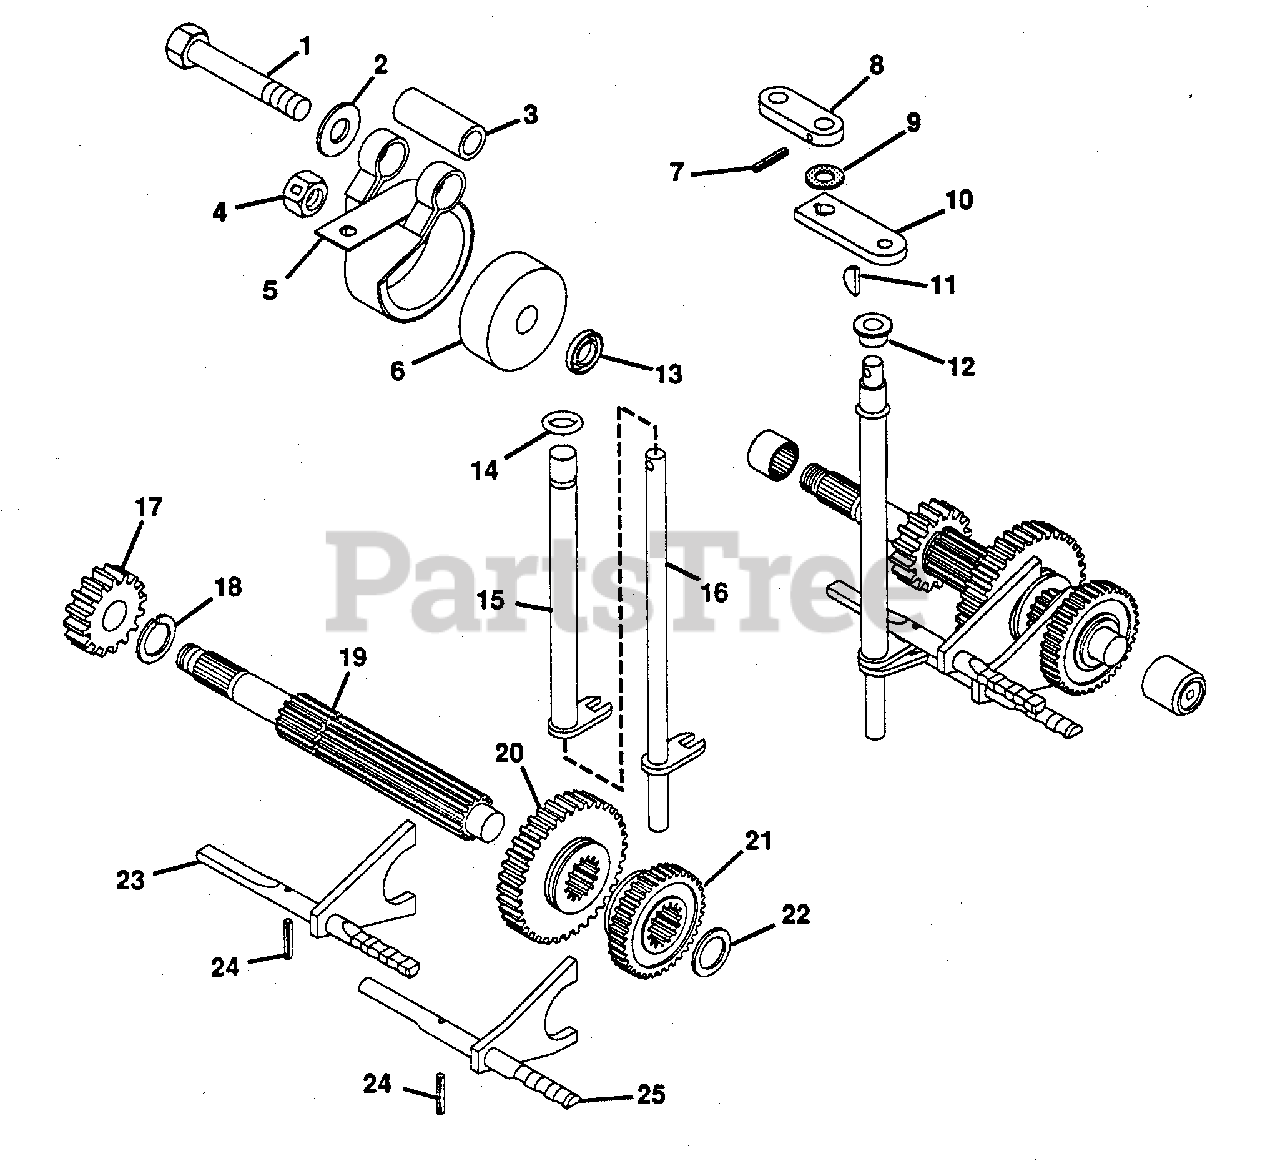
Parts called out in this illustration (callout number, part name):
1	Bolt, Hex 1/2-13 x 2.75
2	Washer, Flat .531 x 1.062 x .095
3	Bushing, .530 x .750 x 2.06
4	Nut, Lock 5/8-11
5	Assembly, Brake Band
6	Drum, Brake
7	Pin, Spring .188 x 1.000
8	Arm, Shifter
9	Washer, Felt (Special for Trans.)
10	Arm, Shifter
11	Key, Woodruff .125 x .375 Hard
12	Bushing, .756 x 1.125 x .75
13	Seal, Oil .750 x 1.254 x .188
14	O-Ring, 5/8 x 3/4 x 1/16
15	Weldment, 1st and 3rd Shifter
16	Weldment, 2nd and 4th Shifter
17	Gera, 8 DP 16 Teeth x .850
18	Ring, Retaining 1.00 Shaft
19	Shaft, Slide Gear
20	Gear, Sliding 10 DP 36 Teeth x .59
21	Gear, Sliding 10 DP 30 Teeth x .59
22	Race, BRG Thrust .752 x 1.240 x .095
23	Wldmt, Rail Shift Fork 1&3 Range
24	Pin, Spring .25 x .75
25	Wldmt, Rail Shift Fork 2&4 Range
